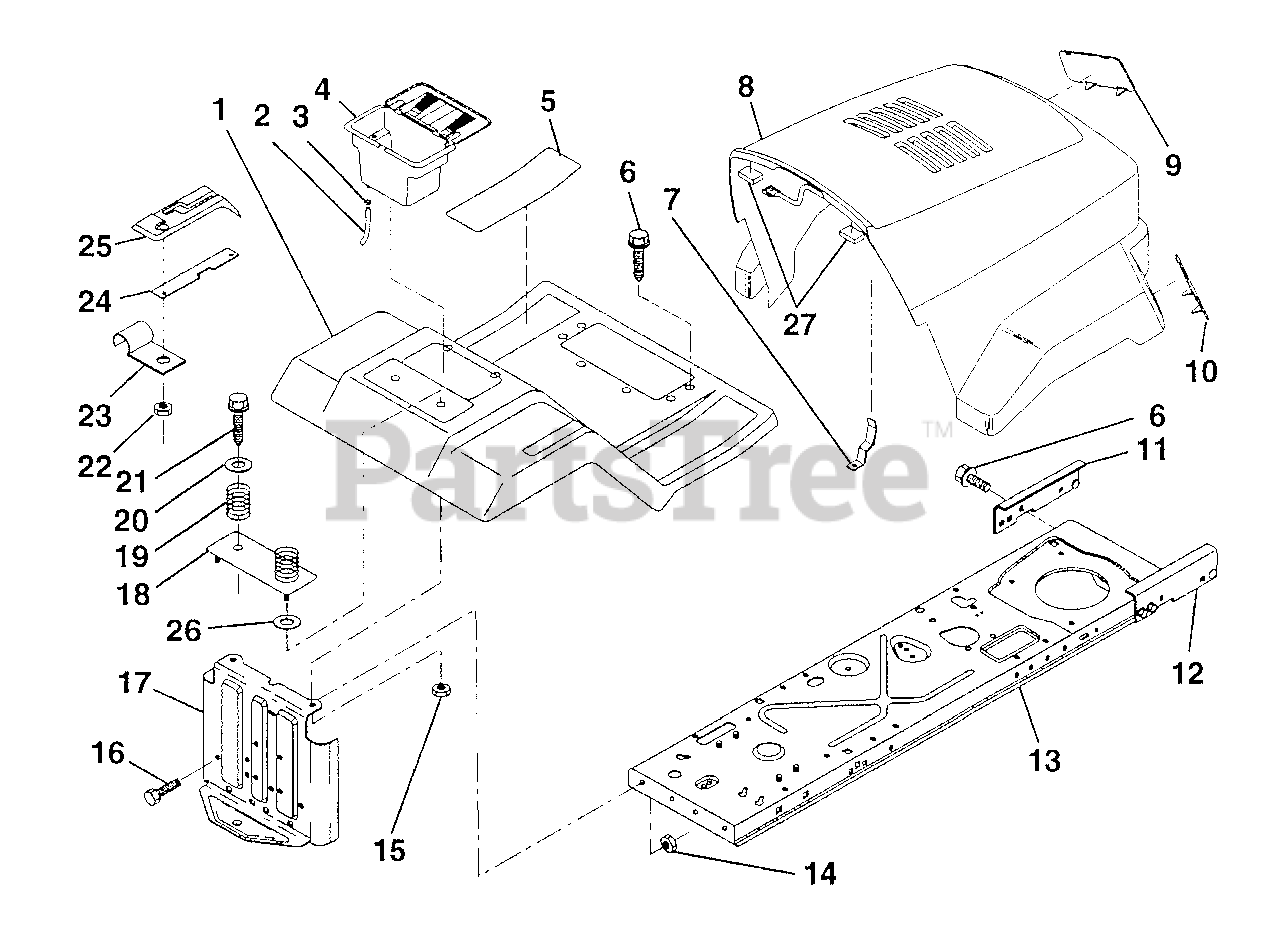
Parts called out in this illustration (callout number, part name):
1	Fender/Footrest
2	Tube, Battery Drain
3	Clamp, Hose
4	Case, Battery
5	Pad, Footrest
6	Screw, Hex Wsh. Thrdrol. 5/16-18 x 3/4
7	Latch, Hood
8	Hood/Grill Asm.
9	Lens, L.H.
10	Lens, R.H.
11	Bracket, Asm. Pivot Frame, L.H.
12	Bracket, Asm. Pivot Frame, R.H.
13	Assembly, Frame
14	Nut, Crownlock 5/16-18
15	Nut, Crownlock 1/4-20 UNC
16	Bolt, Hex Hd. 5/16-18 U NC x 3/4
18	Plate, Asm. Battery
19	Spring, Compression, Seat
20	Washer 13/32 x 1-1/4 x 12 Ga.
21	Bolt, Hex 3/8-16 Tapping
22	Nut, Self-Threading, Washer Head 3/16
23	Clip, Insulated
24	Bar, Shift Lock
25	Console, Shift Control
26	Washer 9/32 x 7/8 x 13 Ga.
27	Bumper, Hood
